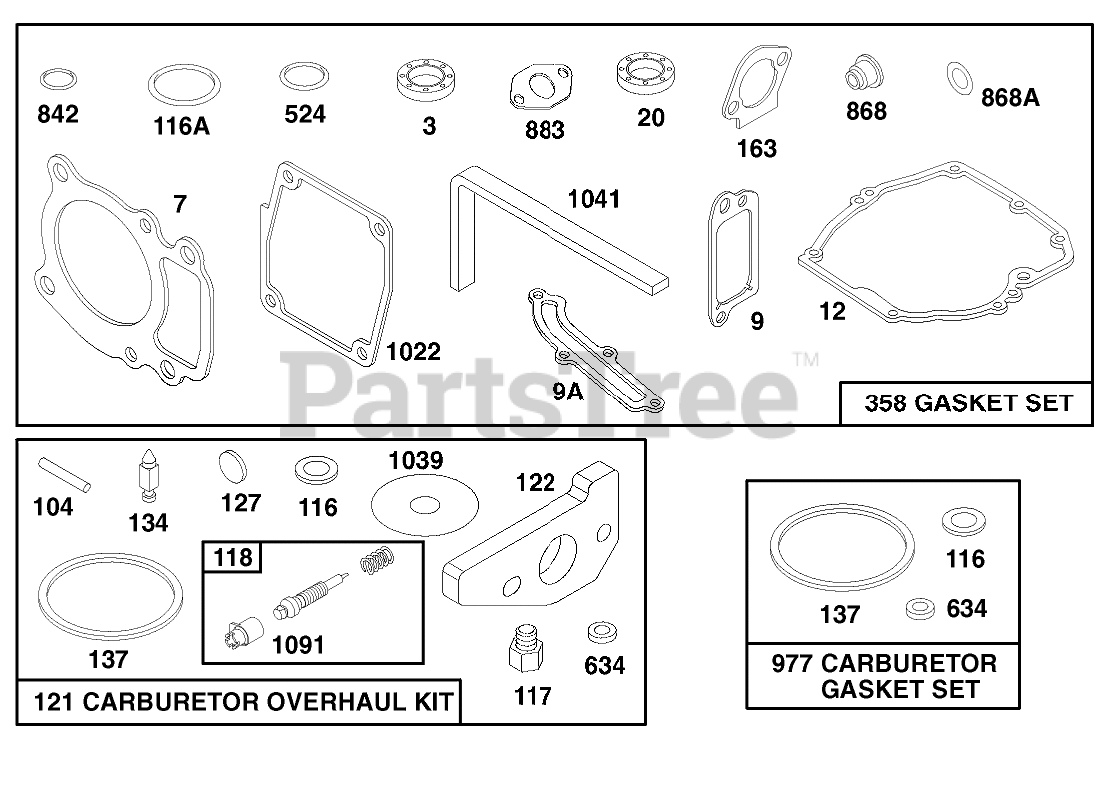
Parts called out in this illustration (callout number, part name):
3	SEAL - OIL
7	CYLINDER HEAD GASKET
9	BREATHER GASKET
9A	GASKET-BREATHER
12	ENGINE BASE GASKET
20	SEAL-OIL
37	GUARD - FLYWHEEL
104	FLOAT HINGE PIN
116	SEALING GASKET
116A	O RING SEAL
117	Jet-Main
118	VALVE/SPRING - NEEDLE
121	KIT-CARBURETOR OVERHAUL
122	ADAPTER ASSEMBLY
127	PLUG - WELCH
134	Valve-Inlet (Includes Seat)
137	FLOAT BOWL GASKET
163	AIR CLEANER GASKET
358	GASKET SET
524	O-RING
634	SEAL WASHER
842	O-RING
868	SealAssy-Valve
868A	Seal-Valve
883	EXHAUST GASKET
977	CARBURATOR GASKET SET
1022	ROCKER COVER GASKET
1039	FLOAT LIMITER
1041	SEAL - FOAM
1091	CAP - LIMITER
